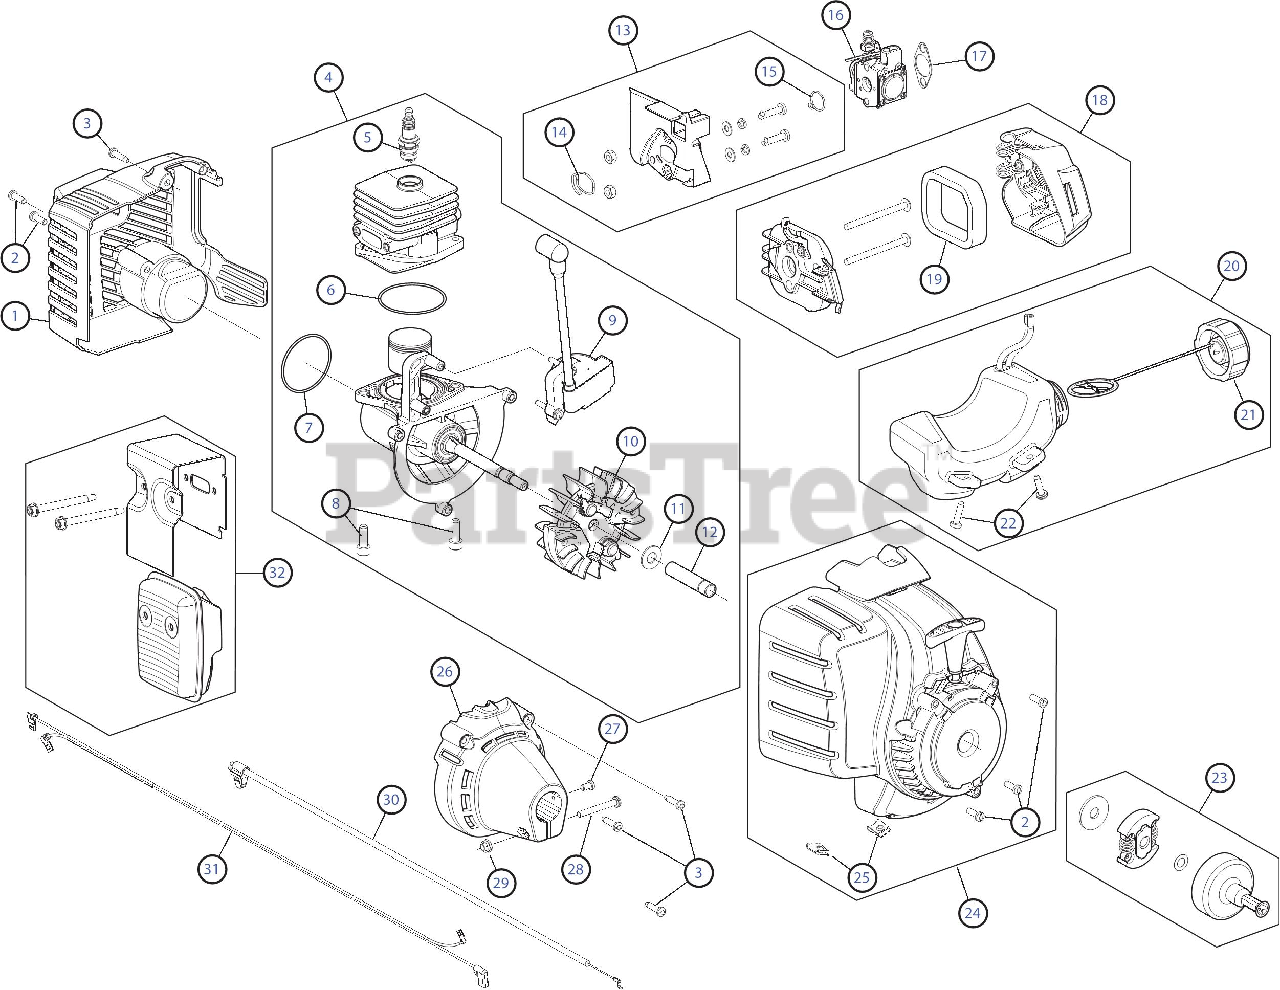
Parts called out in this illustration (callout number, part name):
1	Rear Cover Assembly (Incl. 2 & 3)
2	Housing Screw
3	Cover Screw
4	Short Block Assembly (Incl. 5 - 12)
5	Spark Plug
6	Crankcase O-Ring
7	O-Ring
8	Crankcase Bolt
9	Module Assembly
10	Flywheel Assembly
11	Washer
12	Spacer
13	Insulator Assembly (Incl. 14 & 15)
14	Insulator O-Ring
15	Carburetor O-Ring
16	Carburetor
17	Air Cleaner Gasket
18	Air Cleaner Cover Assembly (Incl. 19)
19	Air Cleaner Filter
20	Fuel Tank Assembly (Incl. 21 & 22)
21	Fuel Tank Cap
22	Fuel Tank Screw
23	Clutch Assembly
24	Starter Housing (Incl. 2 & 25)
25	U-shaped Nut
26	Clutch Cover (Incl. 3)
27	Anti-rotation Screw
28	Clamp Screw
29	Clamp Nut
30	Throttle Cable
31	Lead Wires
32	Muffler Assembly
